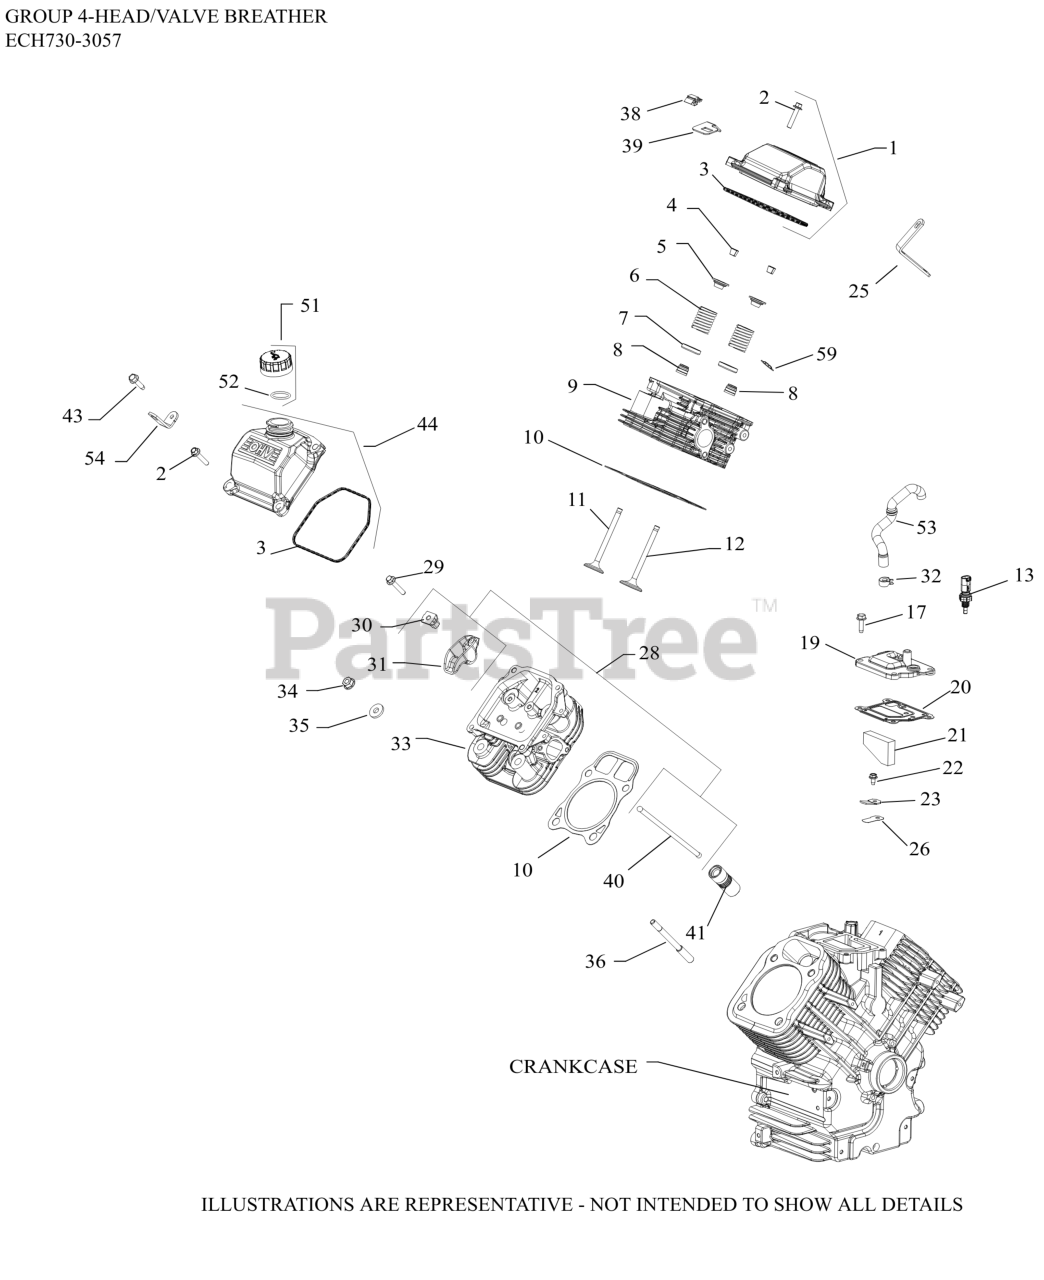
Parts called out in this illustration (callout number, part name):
1	KIT, VALVE COVER-PLAIN (PLASTIC)
2	SCREW, FLG M6X1.0X30
3	O-RING (YELLOW), VALVE CO
4	KIT, RETAINER
5	CAP, VALVE SPRING
6	SPRING, VALVE
7	RETAINER, SPRING
8	SEAL, VALVE BAND
9	KIT, CYLINDER HEAD (#1)-(#2481803S)
10	KIT, GASKET CYLINDER HEAD
11	VALVE, EXHAUST
11	VALVE, EXHAUST (.25)
12	VALVE, INTAKE (STD)
12	VALVE, INTAKE (.25)
13	SENSOR, TEMPERATURE
17	SCREW, THREAD FORMING
19	COVER, BREATHER
20	GASKET, BREATHER
21	FILTER, BREATHER
22	SCREW, FLG THD FRM M5X.8X10
23	RETAINER, REED
25	STRAP, LIFT
26	REED, BREATHER-(#2440206S)
26	REED, BREATHER
28	KIT, VALVE TRAIN
29	SCREW, FLG (BLACK) M6X1.0X34
30	PIVOT, ROCKER ARM
31	ARM, ROCKER
32	SPRING CLAMP, HOSE
33	KIT, CYLINDER HEAD (#2)-(#2481804S)
34	NUT, FLG M8X1.25
35	WASHER, FLAT 8.6 MM
36	STUD, M8X1.25
38	CLIP, O2 SENSOR
39	BRACKET, OXYGEN SENSOR
40	ROD, PUSH
41	LIFTER, VALVE HYDRAULIC-USE 25 351 11-S
43	SCREW, THREAD FORMING
44	KIT, VALVE COVER-OIL FILL
51	KIT, OIL FILL CAP (YELLOW)
52	O-RING, DIPSTICK
53	BREATHER, HOSE (EFI H/S, LPAC)
54	STRAP, LIFTING
59	RETAINER, VALVE GUIDE (KM)
